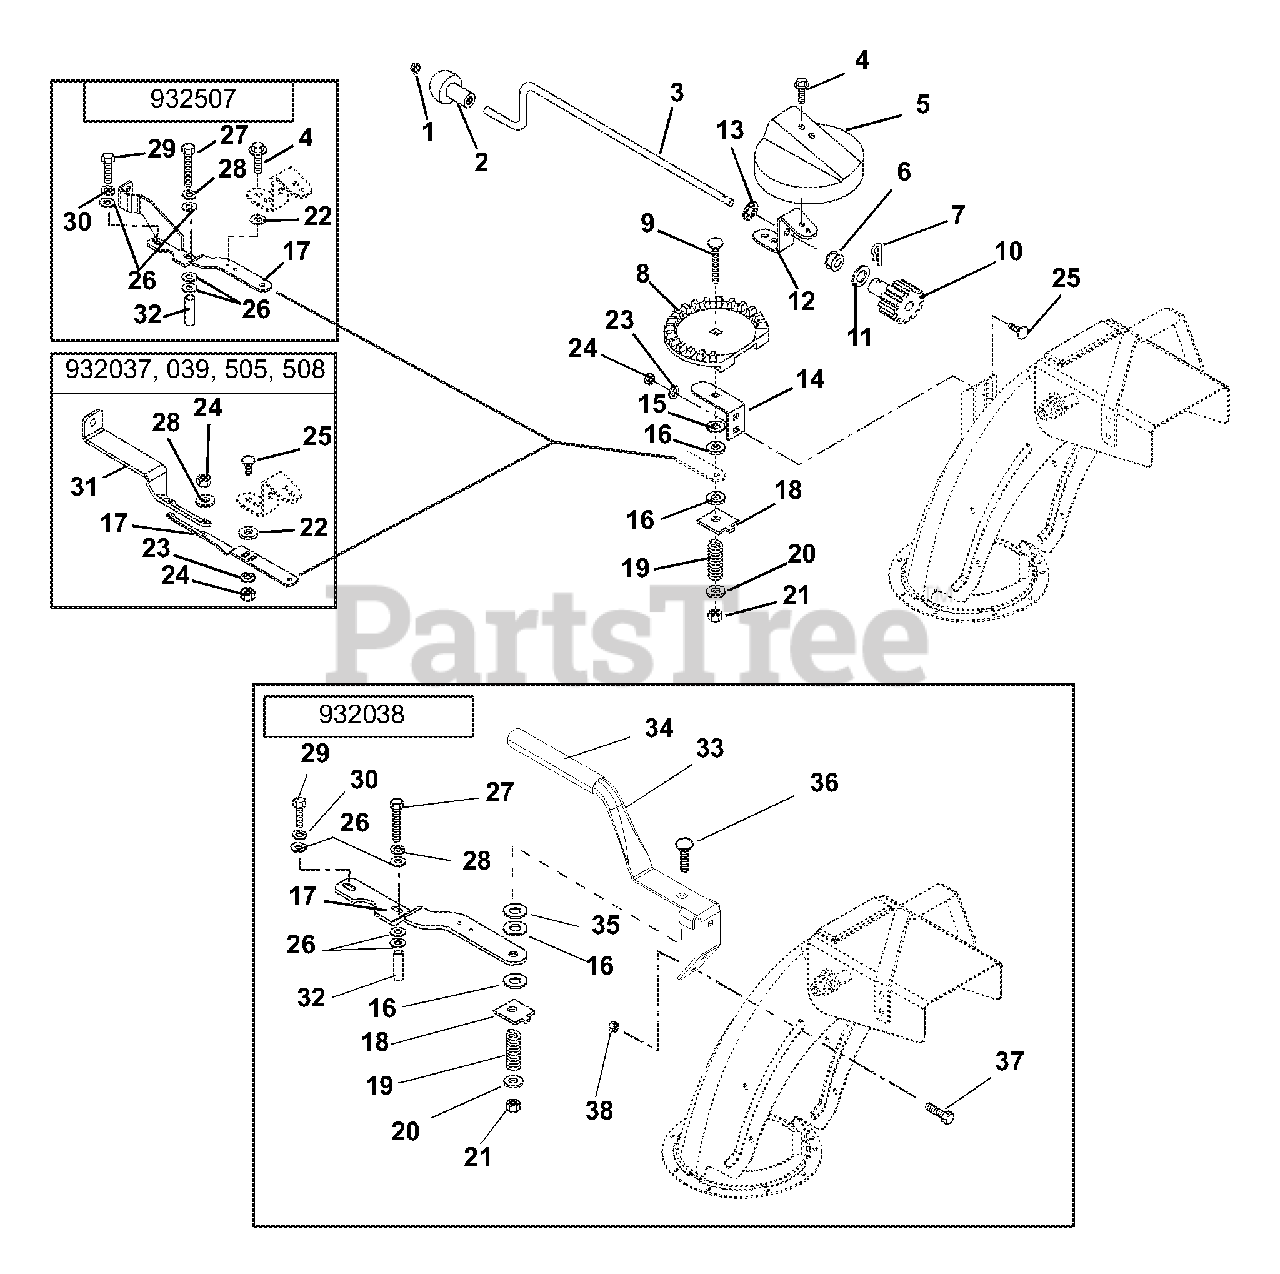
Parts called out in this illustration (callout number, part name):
1	CAP, 3/8 ROD YWZC
2	KNOB
3	CRANK, CHUTE
4	@SCR-TAP .25-20X.50 HWH TR YWZ
5	GEAR COVER
6	BUSHING, POLYLINER-.63 SNAPIN
7	PIN, SPRING CLIP
8	CHUTE GEAR
9	@BLT-RDHDSQNK .38-16X2.50 G5YZ
10	BRACKET, W/PINION GEAR
11	WSHR-THRST .625 X 1.0 X .03
12	BRACKET, PINION GEAR
13	PUSHNUT .625
14	GEAR STRAP
15	WSHR-FL-STL .380X1.50X.062 YWZ
16	FRICTION WASHER
17	BRACKET, CRANK SUPPORT
17	BRACKET, CHUTE SUPPORT
17	BRACE, CHUTE CONTROL
18	FRICTION PLATE
19	SG-COMP .187X.56X1.62
20	@WSHR-FL-STL.406X.812X.065 YWZ
21	@NUT-LK-CTR .38-16 YWZC
22	@WSHR-FL-STL.281X.62X.065 YWZC
23	@WSHR-LK .25X.062 REG YWZC
24	@NUT-HEX .25-20 YWZC
25	@BLT-RDHDSQNK .25-20X.75 G5YZ
26	WSHR-FL-STL .328X.875X.062YWZC
27	@BLT-HEX .25-20X1.50 GR5 YWZC
28	WSHR-LK .250X.077 HVY YWZC
29	@BLT-HEX .31-18X.75 GR5 YWZC
30	WSHR-LK .312X.097 HVY YWZC
31	SUPPORT, CHUTE CRANK
32	SPACER .280X.625X.640
33	CHUTE HANDLE, PAINTED
34	GRIP, CHUTE HANDLE, ORANGE
35	@WSHR-FL-STL.563X1.38X.109YWZC
36	@BLT-RDHDSQNK .38-16X2.25 G5YZ
37	@BLT-HEX .25-20X.50 GR5 YWZC
38	@NUT-LK-CTR .25-20 YWZC
